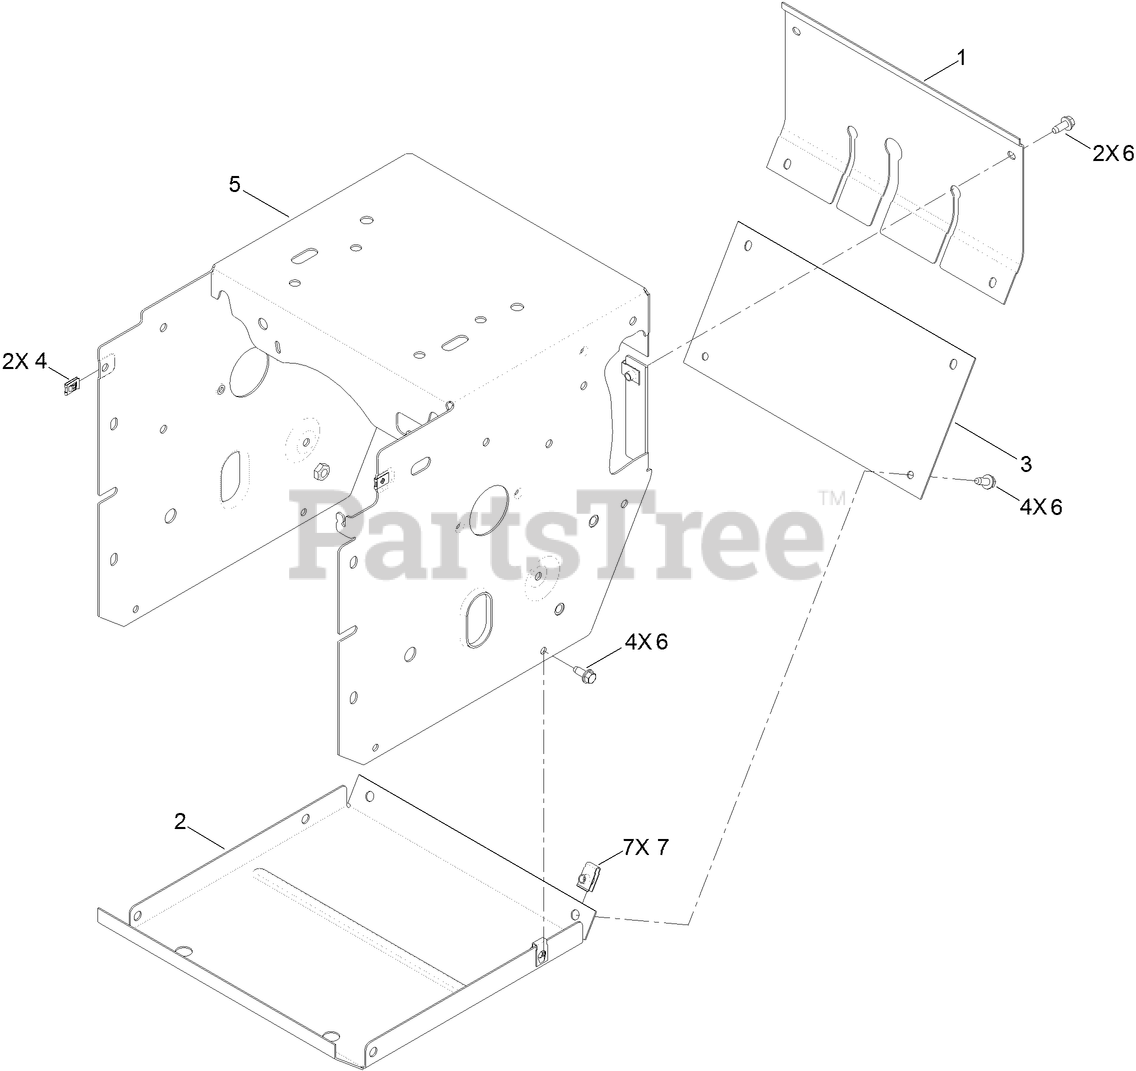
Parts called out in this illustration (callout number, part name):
1	COVER-UPPER
2	PAN-BOTTOM
3	COVER-LOWER
4	NUT-SPEED
5	FRAME-TRACTION
6	SCREW-HWH
